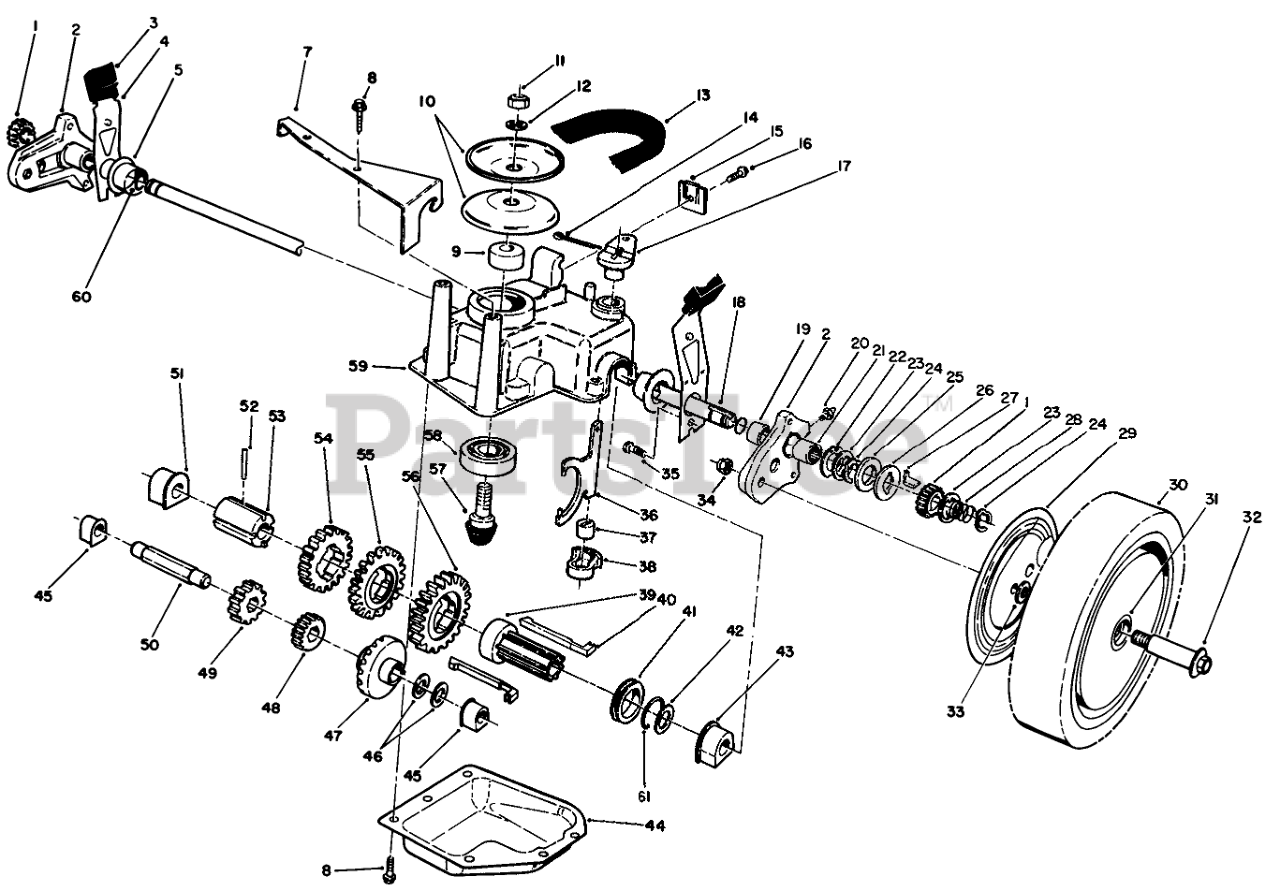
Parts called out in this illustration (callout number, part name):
1	GEAR-PINION
2	Pivot Arm Assembly (Incl. Ref. #19, 20, 21)
3	KNOB-ARM
4	SPRING ARM ASM SP
5	CAP-END
7	Bracket-Guide
8	SCREW-HWHTF
9	SPACER
10	Pulley Half
11	NUT-HEX
12	WASHER-FLAT
13	V-BELT E
14	PIN-COTTER
15	Cable Clamp
16	SCREW-HWHTF
17	SHIFT LEVER
18	SHAFT-OUTPUT
19	BUSHING
20	FITTING-GREASE
21	BEARING-ROLLER
22	WASHER-ARM, PIVOT
23	WASHER-THRUST, KEYED
24	RING-CLIP, LOCKING
25	RING-FRICTION
26	WASHER-CLUTCH
27	KEY-ROCKING, LH
28	SPRING-COMPRESSION
29	WHEEL COVER
30	Wheel-Tire & Gear Assy. (Incl. Ref. #31)
31	HOC ADJUSTMENT ASM
32	WHEEL BOLT
33	WASHER
34	Nut
35	SCREW-HWH
36	YOKE-SHIFT
37	BUSHING-YOKE
38	RETAINER-FORK, SHIFT
39	SHIFT KEY SLEEVE
40	Key Shift
41	SHIFT COLLAR
42	WASHER-PLAIN
43	BUSHING-OUTPUT
44	Cover-Gearcase
45	BUSHING
46	WASHER-THRUST
47	Gear-Bevel
48	PINION-20T
49	PINION-25T
50	SHAFT-INTERMEDIATE
51	BUSHING
52	PIN-SPRING
53	SLEEVE-GEAR
54	GEAR-39T
55	GEAR-44T
56	GEAR-49T
57	Gear-Pinion
58	BEARING-BALL
59	CASE-GEAR, UPPER
60	O-RING
61	CLIP-SPRING
